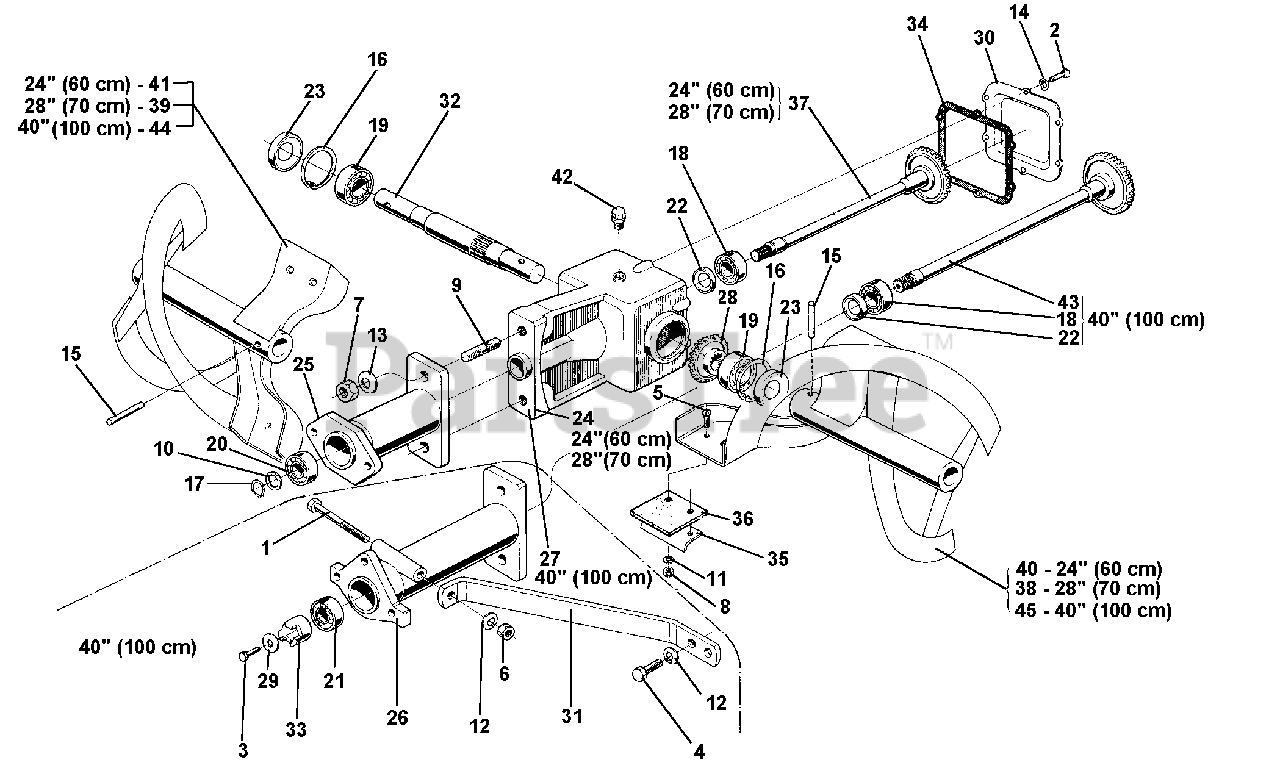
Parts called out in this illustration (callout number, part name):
1	SCREW TE M10 X 110
2	SCREW M6 X 12
3	SCREW TE M6 X 16
4	SCREW TE M10 X 25 UNI 5739-8G
5	SCREW TSVEI M6 X 20
7	NUT M16 UNI 5588-5S
8	SELF LOCKING NUT M6
11	WASHER, FLAT 6.4
12	SUPER WASHER 10 DIN 6796
13	SUPER WASHER
14	WASHER, LOCK 6.4
15	PIN, LOCKING 10 X 50 DIN 1481
16	CIRCLIP, INTERN D 62
17	CIRCLIP, EXTERN D 20
18	BEARING 25 X 52 X 15 6205
19	BEARING 30 X 62 X 16 6206
20	BEARING 20 X 47 X 14 6204 2RS ST
21	BEARING 25 X 47 X 12 ST 2RS 6005
22	OIL SEAL 25 X 40 X 7
23	SEAL, OIL 30 X 62 X 10 STANDARD
24	SNOW THROWER CASING
26	LONG COUPLING
27	SNOW THROWER LONG CASING
29	WASHER 7 X25 X 4
30	SNOW THROWER CASING COVER
32	TURBINE SHAFT
33	3-TOOTH COUPLING
34	SNOW THROWER CASING GASKET
36	RUBBER FLAP
37	DRIVE SHAFT
38	BLADE 95 CM
39	LEFT TURBINE 70 CM
40	RIGHT TURBINE 60 CM
41	LEFT TURBINE 60 CM
42	BREATHER CAP 1/4 GAS
44	LEFT TURBINE 100 CM
45	RIGHT TURBINE 100 CM
